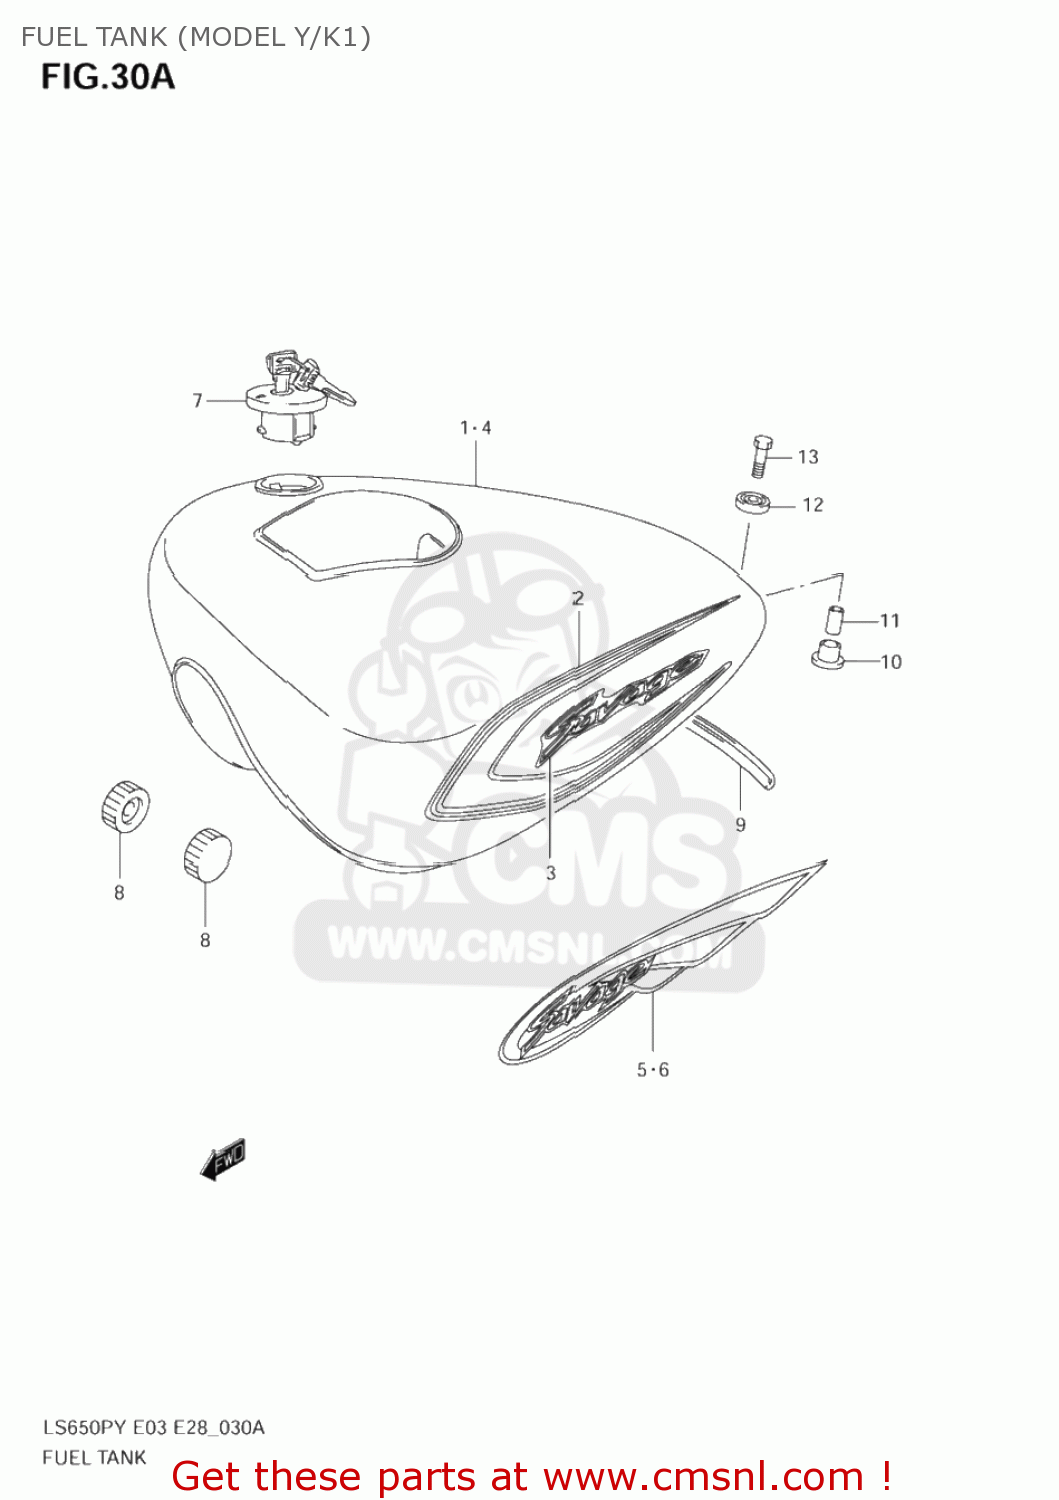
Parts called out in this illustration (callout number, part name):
1	TANK ASSEMBLY,FUEL
2	TAPE SET,FUEL TANK
3	EMBLEM,FUEL TANK
4	TANK ASSY,FUEL(BLACK)
5	EMBLEM,FUEL TANK,R
6	EMBLEM,FUEL TANK,L
7	CAP SET,FUEL TANK
8	CUSHION
9	MOLDING,FUEL TANK RR
10	CUSHION
11	SPACER(6.5X9X18)
12	CUSHION
13	BOLT
